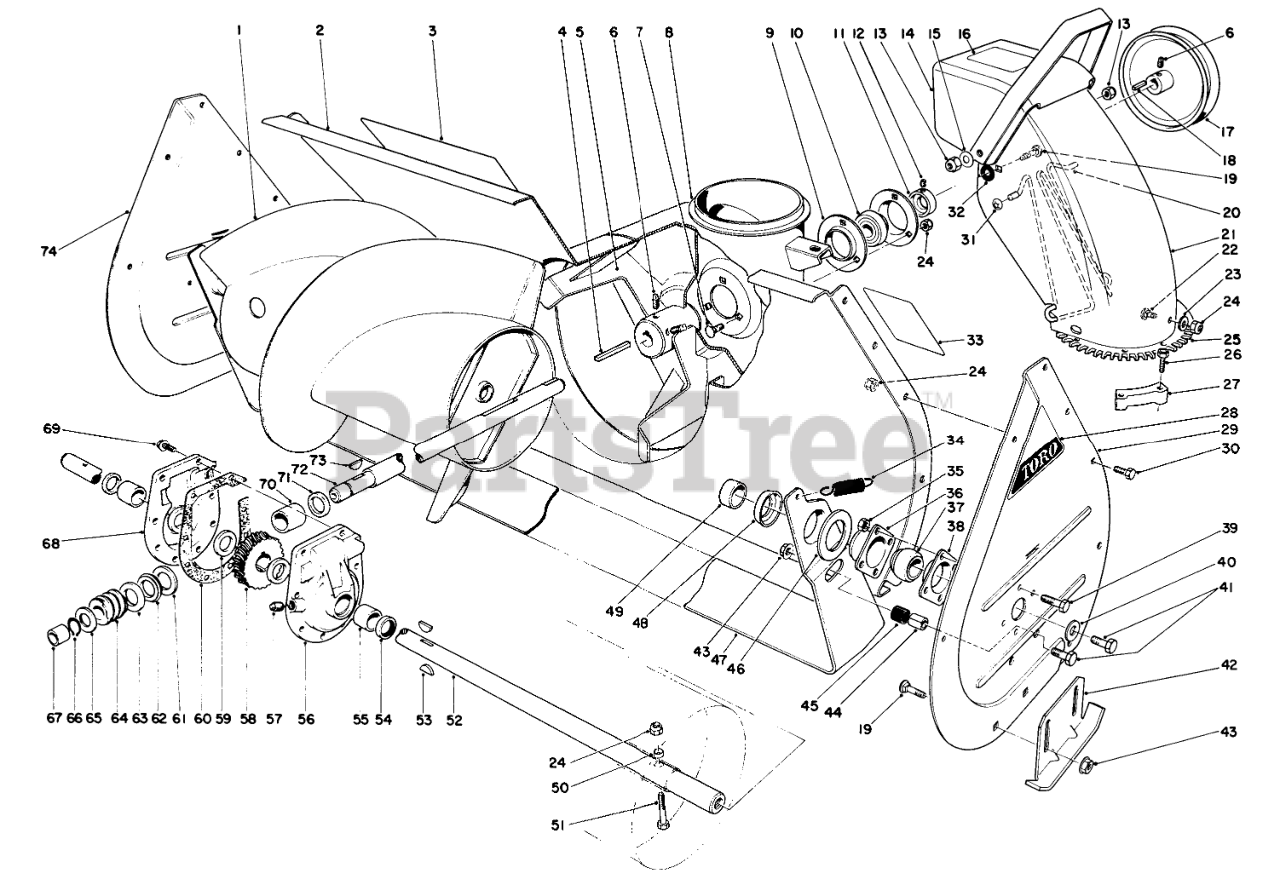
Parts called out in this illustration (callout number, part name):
1	RH AUGER ASM - 32"
2	AUGER HSG WA 32" R
3	AUGER WARNING DECAL
5	IMPELLER ASM
6	SCREW-SET, SQH
7	BOLT-CARR
8	CHUTE RING
9	BRG FLANGE
10	BALL BRG W/COLLAR
11	EXT LOCKING COLLAR
12	SCREW-HSH
13	NUT-LOCK, CONE
14	Deflector (Incl. Ref. #16)
15	WASHER-BELLEVILLE
16	Decal-Danger
17	1/2 X 9.5 DIA PULLEY
18	SQUARE KEY
19	SCREW-CARR
20	CHUTE WIRE
21	Chute-Upper
22	SCREW-CARR
23	WASHER-PLAIN
24	NUT-LOCK, NI
25	Screw
26	SCREW-SPECIAL
27	RETAINER-CHUTE
28	AUGER SIDE PLT DECAL
29	LH AUGER SIDE PLT R
30	SCREW-HH
31	NUT-PUSH
32	WASHER-RUBBER
33	DECAL-WARNING, AUGER
34	SPRING-TENSION
35	NUT-LOCK, CONE
36	BEARING-FLANGE, FRONT
37	BEARING
38	BEARING-FLANGE, REAR
39	SCREW-HH
40	WASHER
41	SCREW-HH
42	AUGER SKID WA R
43	NUT-HF
44	SCRAPER STOP SPACER
45	SCRAPER STOP CUSHION
46	SCRAPER BLADE SPACER
47	SCRAPER BLADE 32" R
48	Positioner-Scraper
49	AUGER SPACER
50	SPACER-HUB, AUGER
51	Auger Bolt
52	32 AUGER SHAFT
53	KEY-WOODRUFF
54	SEAL-OIL
55	BUSHING
56	Gear Case L.H. (Incl. Ref. #54-55)
57	PLUG-PIPE, SQH
58	GEAR-WORM, 27T
59	WASHER-THRUST
60	GASKET-CASE, GEAR
61	WASHER-THRUST
62	BEARING-THRUST
63	THRUST-WASHER
65	WASHER-THRUST
66	Ring-Snap
67	BUSHING
68	Gear Case R.H. (Incl. Ref. #54-55)
69	SCREW-TAPTITE
70	BUSHING-SPECIAL
71	RING-QUAD
72	SHAFT-IMPELLER
73	KEY-WOODRUFF
74	RH AUGER SIDE PLT R
